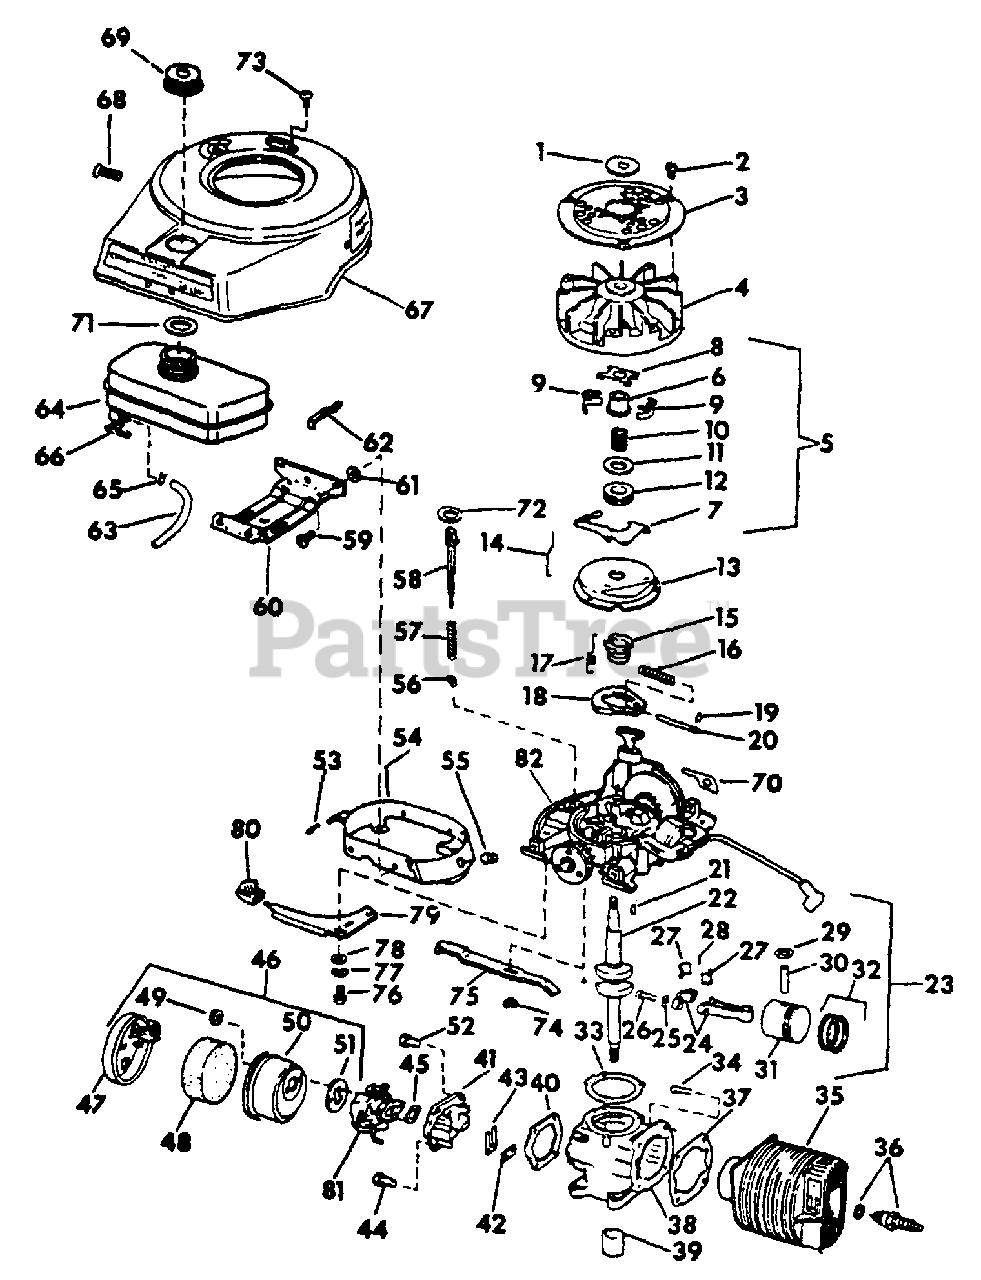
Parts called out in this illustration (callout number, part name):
2	SCREW, THD CUTTING
3	SCREEN, FLYWHEEL
5	GOVERNOR ASSY
6	COLLAR, GOVERNOR
7	LEVER, GOVERNOR
8	YOKE, GOVERNOR
9	WEIGHT, GOVERNOR
10	SPRING, GOVERNOR
11	WASHER, THRUST
12	COLLAR, THRUST
14	ROD, GOVERNOR
15	CAM, SPARK ADVANCE
16	SPRING, SPARK ADVANCE
17	SPRING, VARIABLE SPEED
18	FLYWHEEL, SPARK ADVANCE
19	RETAINER, SPRING
20	PIN, SPARK ADVANCE
21	KEY, CRANKSHAFT
23	PISTON & CONNECTING ROD ASSY
24	ROD ASSY, CONNECTING
25	LOCKPLATE, SCREW
26	SCREW, CONNECTING ROD
27	LINER, CONNECTING ROD
28	BEARING SET, NEEDLE - PACKED
29	RING, RETAINING
32	RING SET, PISTON - 2 RINGS
33	GASKET, CRANKCASE TO ARM PLATE .010
34	SCREW, CYL TO CRANKCASE
35	CYLINDER & SLEEVE
36	SPARK PLUG & GASKET
37	GASKET, CYL TO CRANKCASE
38	CRANKCASE & SEAL ASSY
40	GASKET, REED PLATE
41	REED PLATE ASSY
42	PLATE, BACKUP
44	SCREW, HH REED PLATE TO CRANKCASE
45	GASKET, CARBURETOR
46	FILTER ASSY, AIR
47	CAP - PAINTED WHITE
48	ELEMENT, AIR CHAMBER
50	CHAMBER, AIR - PAINTED WHITE
52	SCREW, HH REED PLATE TO CRANKCASE
53	NUT, COVER MTG
55	GROMMET, COVER MTG
56	BLADE, SWITCH
57	SPRING, SHUTOFF SWITCH
58	BAR, SHUT-OFF & PRIMER
60	BRACKET, FUEL TANK
62	SPRING, FUEL TANK
64	FUEL TANK ASSY
65	CLAMP, FUEL TANK HOSE
66	VALVE & SCREEN, SHUT-OFF
67	COVER, ENGINE
68	SCREW, COVER MTG
69	CAP, GAS TANK
71	GASKET, TANK TO SHROUD
72	NOT USED ON THIS APPLICATION
73	SCREW, SHOULDER
74	WASHER, SPRING
75	LINK, VARIABLE SPEED CONTROL
76	BOLT, SHOULDER SLOT
78	WASHER, PLAIN
79	LEVER, VARIABLE SPEED
80	KNOB, VARIABLE SPEED LEVER
81	CARBURETOR ASSY
82	MAGNETO ASSY
